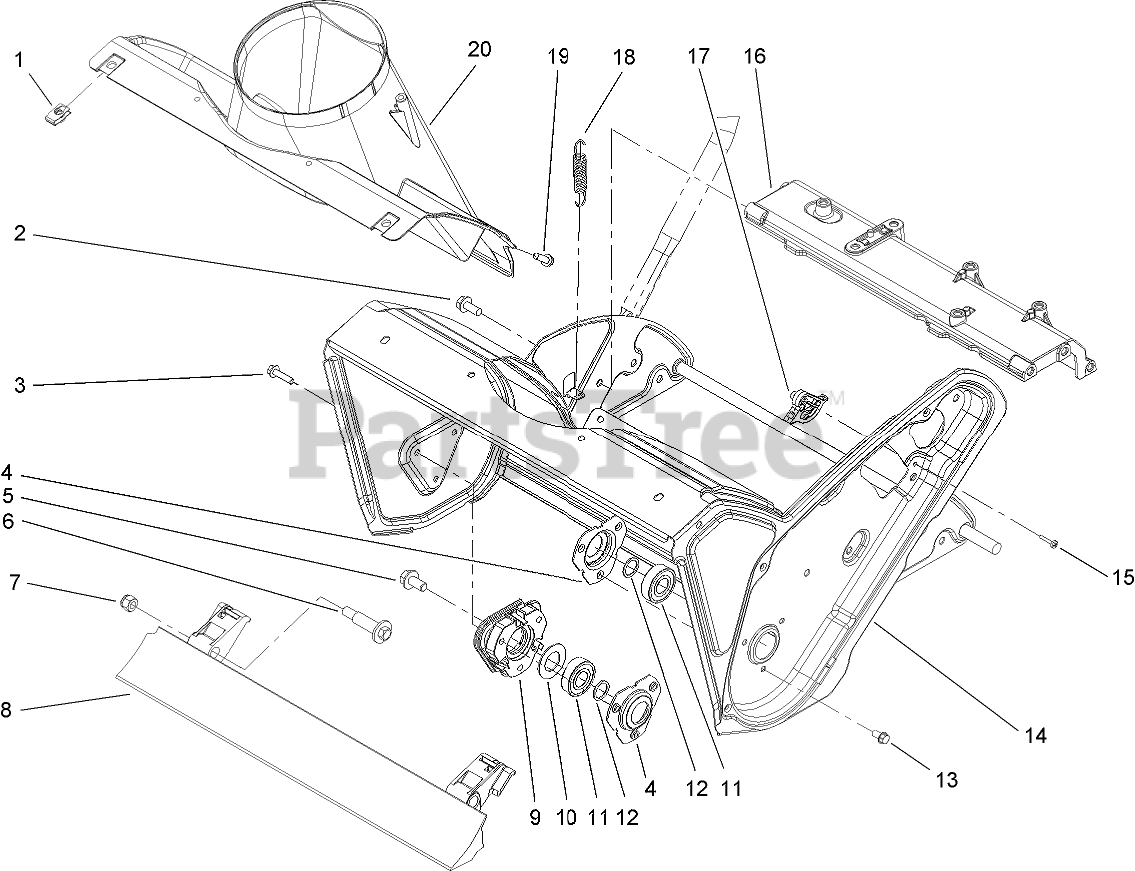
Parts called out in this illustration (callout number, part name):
2	SCREW-HWHTF
3	SCREW-HWHTF
4	FLANGE-BEARING
5	SCREW-HWH
6	BOLT-WHEEL
7	NUT-LOCK, NI
8	BLADE-SCRAPER
9	SPACER-BEARING, RH
10	WASHER-RUBBER
11	BEARING-BALL
12	WASHER-THRUST
13	SCREW-HWH
14	HOUSING-AUGER
15	SCREW-PPH
16	BRACE-FRAME
17	GUIDE-CABLE, CLUTCH
18	SPRING-EXTENSION
19	SCREW-HWH
20	CHUTE-LOWER
